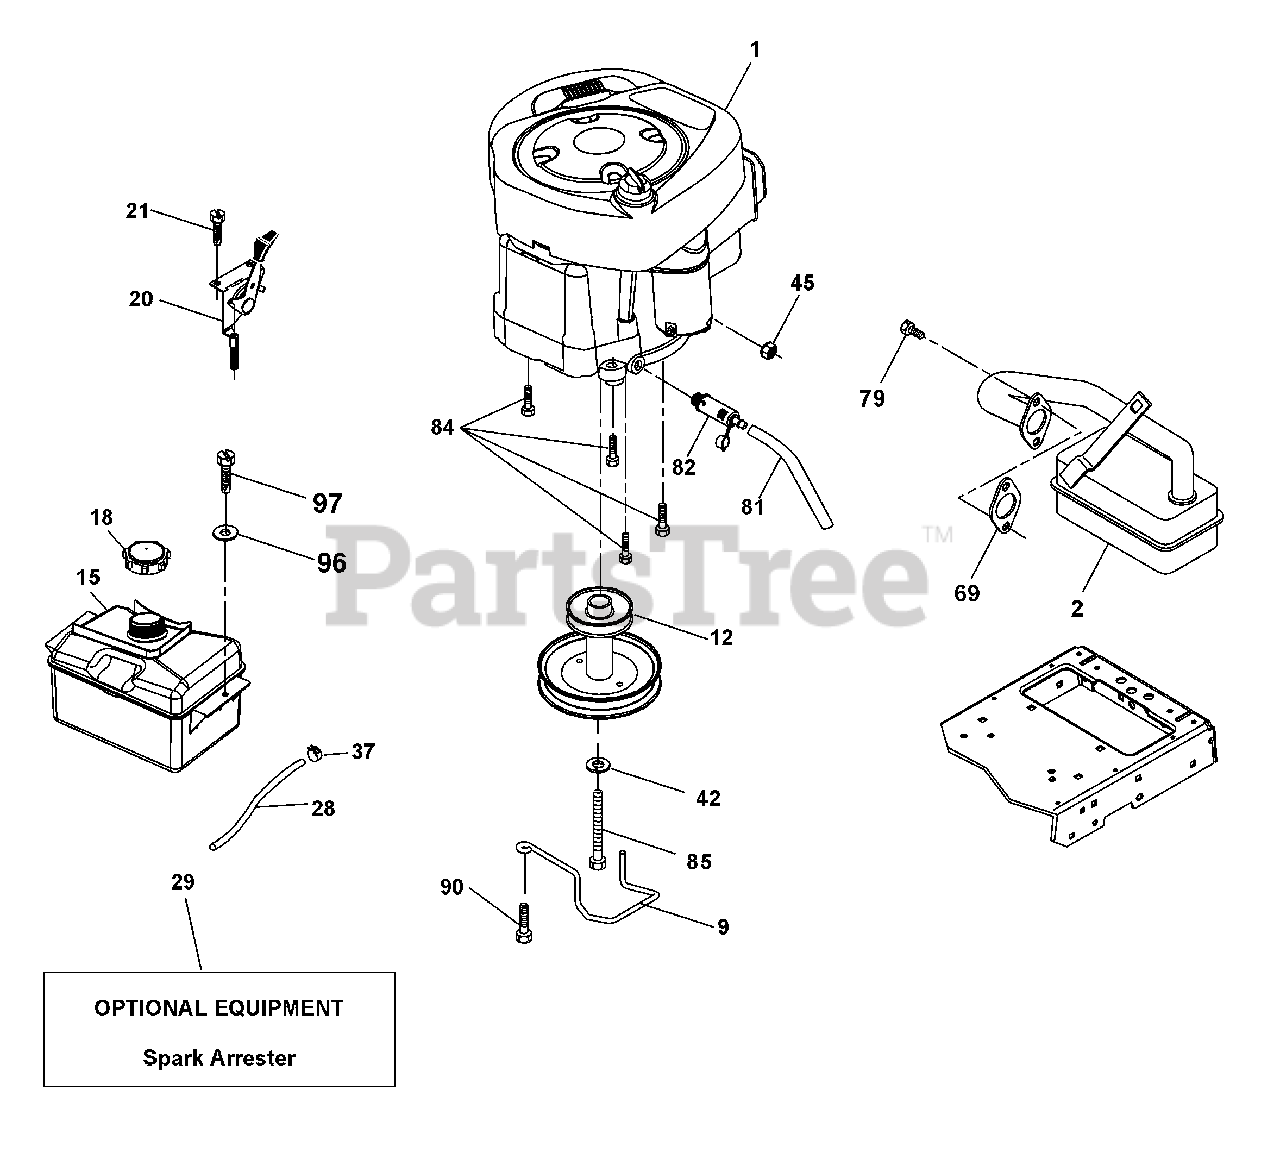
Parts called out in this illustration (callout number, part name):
2	Muffler
9	Keeper Belt Engine
12	Pulley Engine
15	Tank Fuel 1.50
20	Control Throttle/Choke
21	Screw 10 x 3/4 Single Lead-Hex
28	Fuel Line
29	Spark Arrester Kit
37	Clamp Hose
42	Washer Lock 7/16
45	Nut Keps Hex 1/4-20 unc
69	Gasket
79	Screw Socket Hd 5/16-18 x .75
81	Tube Drain Oil Easy
82	Plug Drain Oil
84	Screw 3/8-16 x 1-1/4
85	Bolt Hex 7/16-20 x 4 x Gr. 5-1.5
90	Screw 3/8-16 x 1.0
96	Washer 9/32 x 7/8 x 16 GA
97	Screw 1/4 - 20 x 3/4
